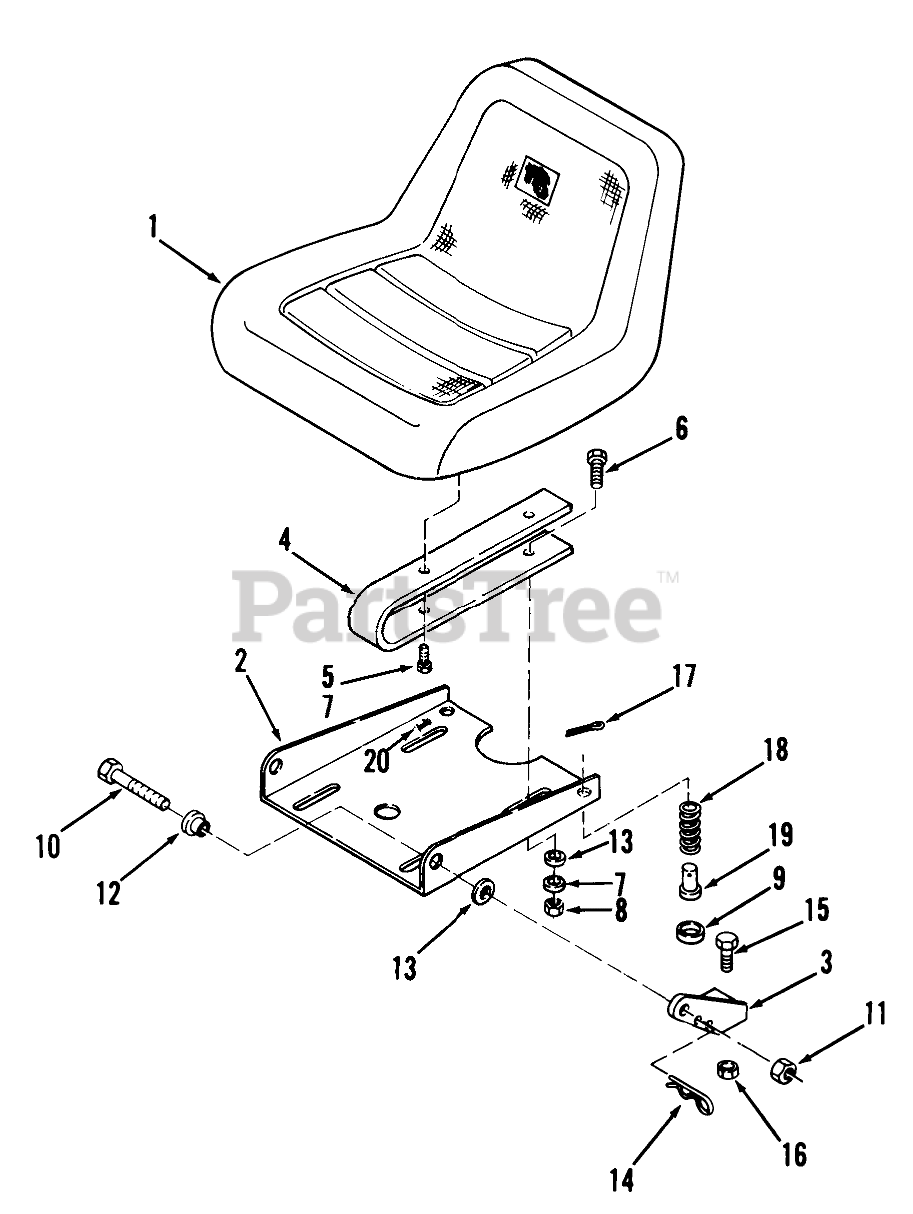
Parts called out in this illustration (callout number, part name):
1	Seat
2	Plate-Seat Pivot
3	Bracket-Pivot LH
3	Bracket-Pivot RH
4	Seat Spring
5	Bolt
6	HHCS
7	Lockwasher
8	Nut
10	Bolt
11	Nut
12	BUSHING
13	WASHER 5/16 SAE
14	Hairpin Cotter
15	Bolt
16	Nut
17	Cotter Pin
18	SPRING
20	BUMPER
